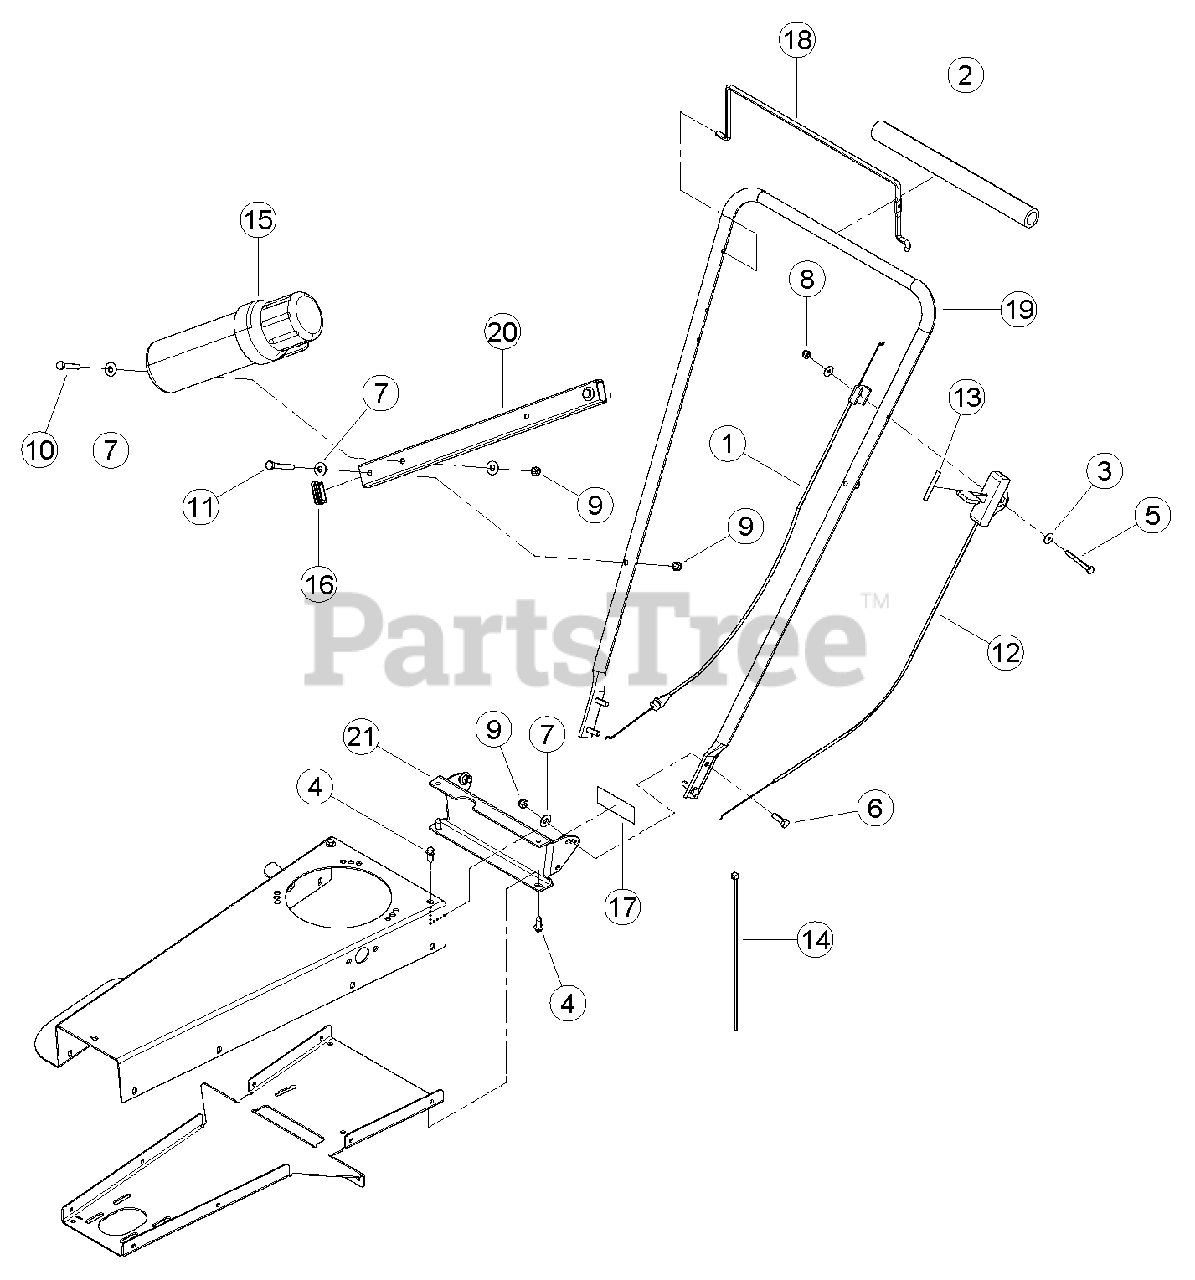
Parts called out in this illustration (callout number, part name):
1	CABLE, BRAKE CONTROL
2	PAD, FOAM HANDLEBAR
3	WASHER, 1/4 FLAT ZP
4	SCREW, 11/32 X 7/8 HWH AB THREAD ZP
5	BOLT, 1/4 X 2-1/4 HCS GR5 ZP (WT160T ONLY)
5	BOLT, 1/4 X 1-1/2 HCS GR5 ZP (WT190T ONLY)
6	BOLT, 5/16 X 1 HHCS GR5 NC ZP
7	WASHER, 5/16 FLAT ZP
8	NUT, 1/4 NE NYLOCK ZP
9	NUT, 5/16 NE NYLOCK ZP
10	BOLT, 5/16-18 X 1-3/4 HCS GR5 ZP
11	BOLT, 5/16 X 2-1/4 HCPS GR5
12	THROTTLE CONTROL (WT160T ONLY)
13	DECAL, THROTTLE (WT160T ONLY)
14	STRAP, 11 IN. BLACK TIE
15	CONTAINER, MANUAL (WAS 18008-00, REMOVED)
16	CAP, PLASTIC 3/4 X 1-1/2 TUBE
17	DECAL, ATLANTIC BRIDGE LTD INFO (WT190T ONLY)
18	BAIL, TRIMMER
19	HANDLEBAR, TRIMMER
20	TUBE, CONTAINER MANUAL
21	CHANNEL, HANDLE SUPPORT
